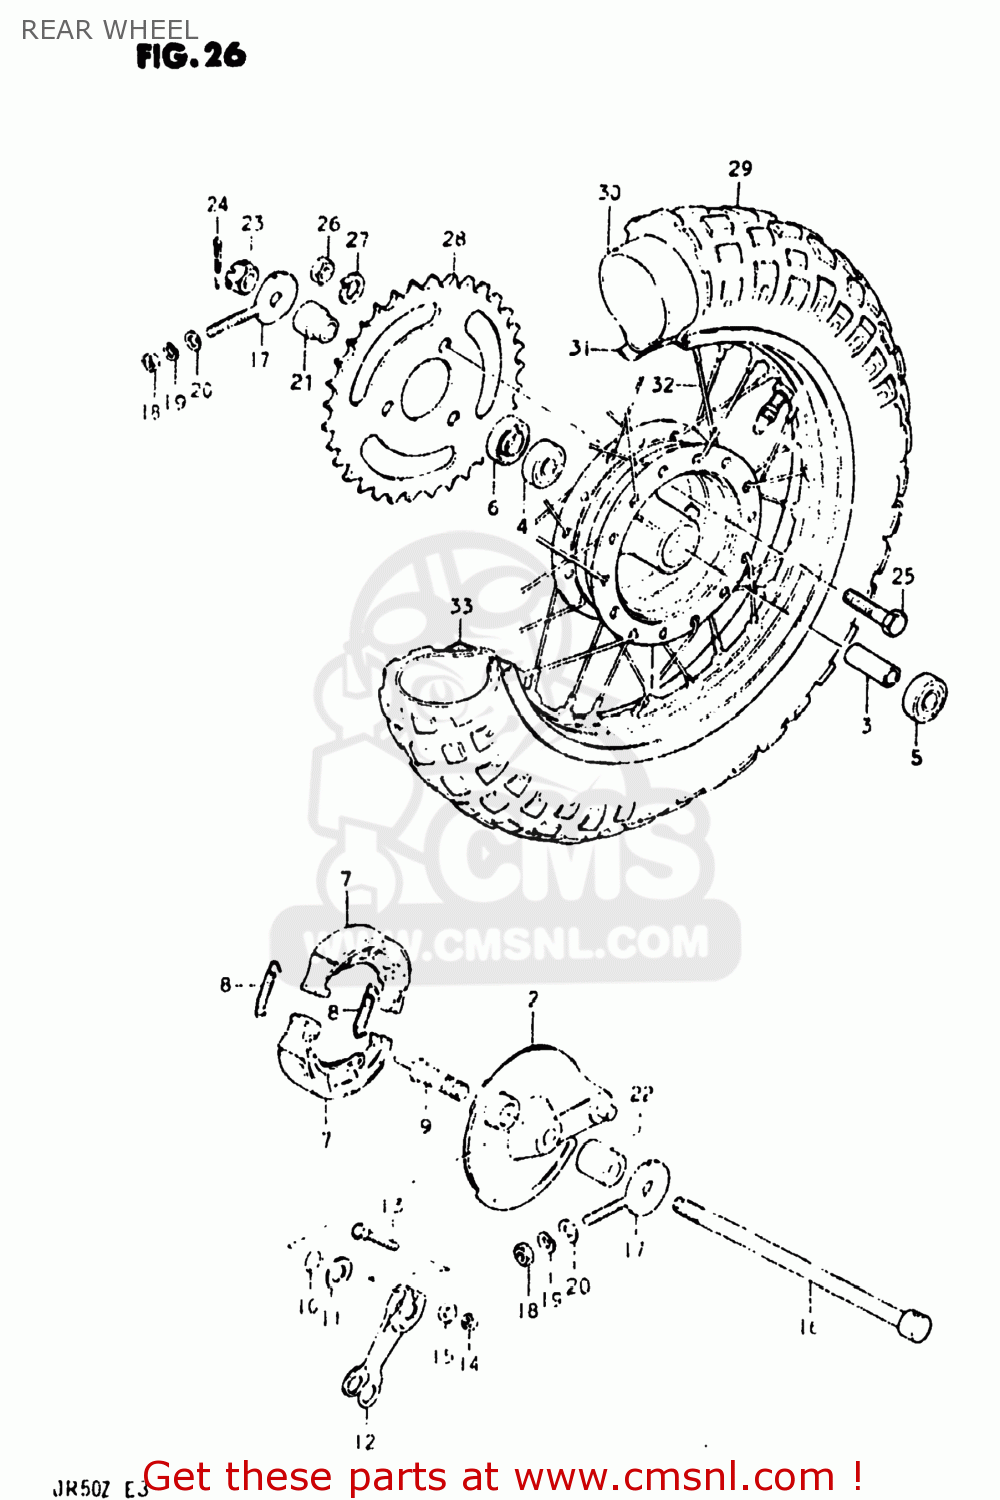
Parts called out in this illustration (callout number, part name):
1	HUB,RR WHEEL
2	PANEL,RR BRAKE ANCHOR
3	SPACER (10.2X16X55)
4	BALL BEARING K
5	BEARING
6	SEAL,OIL(15X27X6)
7	SHOE,BRAKE
8	SPRING(L:34)
9	CAM,FRONT BRAKE
10	O RING(D:2.4,ID:9.8)
11	WASHER (10.5X18X1)
12	LEVER,RR BRAKE CAM
13	BOLT
14	NUT
15	WASHER
16	AXLE,RR
17	ADJUSTER,CHAIN
18	NUT
19	LOCK WASHER
20	WASHER
21	SPACER,RR AXLE,L
22	SPACER,RR AXLE,R
23	NUT
24	PIN 20X20
25	BOLT
26	NUT
27	LOCK WASHER
28	SPROCKET,RR
29	TIRE
30	TUBE,INNER
31	PROTECTOR,INNER TUBE
32	SPOKE SET,RR
33	RIM,WHEEL
